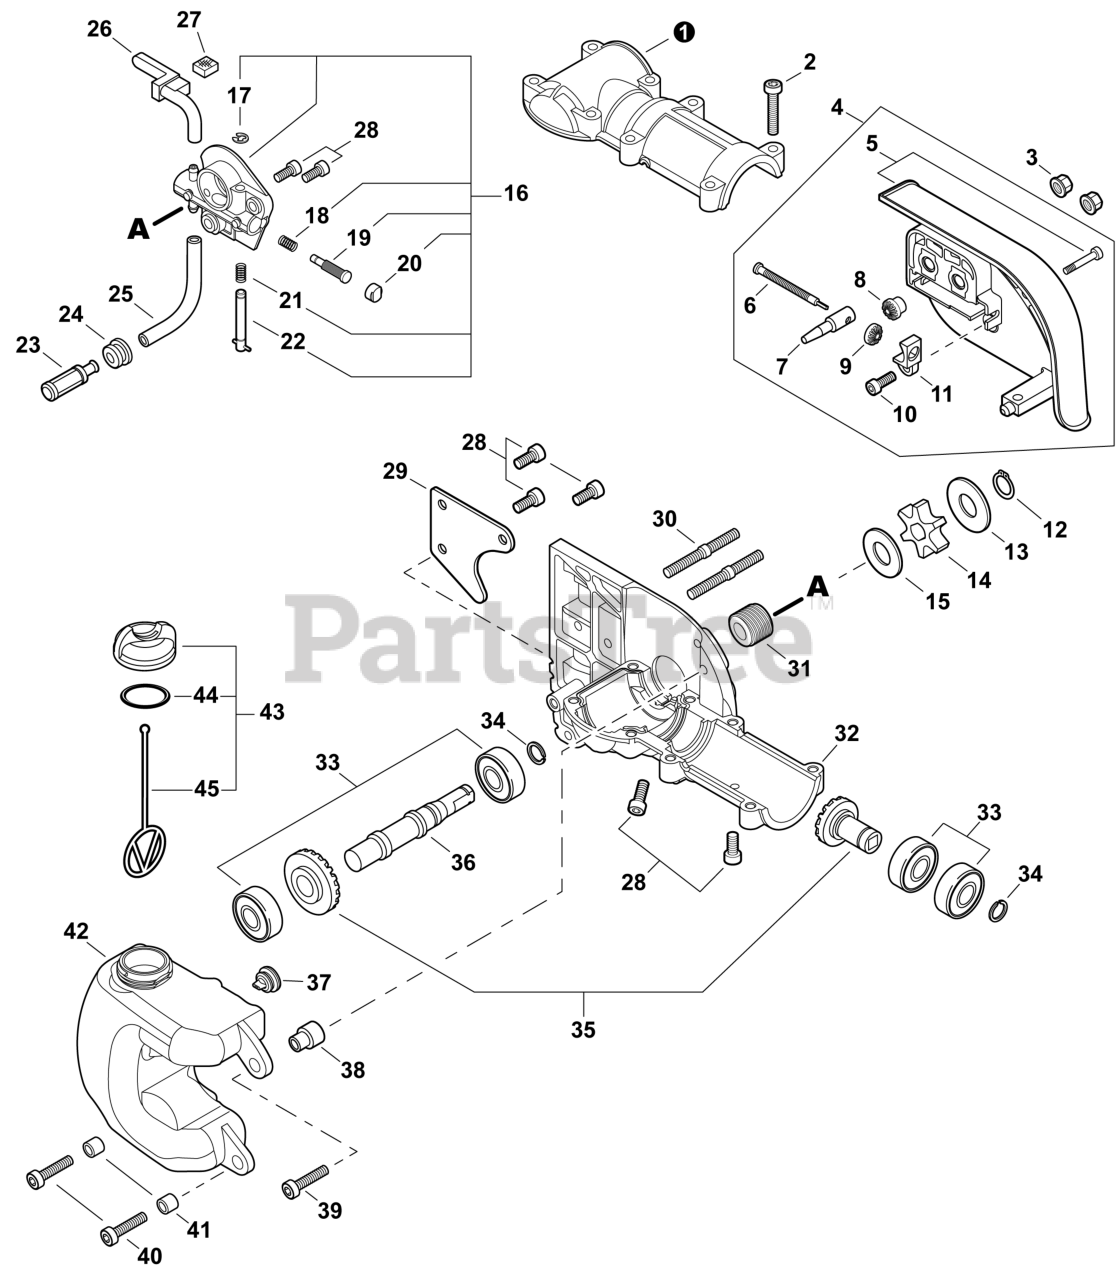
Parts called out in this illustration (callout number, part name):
1	COVER, GEAR CASE
2	BOLT, TORX 5x25
3	NUT, FLANGE M6
4	SPROCKET GUARD ASSY
5	GUARD, SPROCKET
7	TENSIONER, CHAIN
8	GEAR - 14 TOOTH
9	GEAR - 14 TOOTH
10	SCREW 4
11	COLLAR 8
12	RING, SNAP
13	WASHER 10
14	SPROCKET, DRIVE
15	WASHER 10
16	AUTO-OILER ASSY
19	PLUNGER ASSY
20	CAP, PLUNGER
22	ADJUSTER, OILER
23	FILTER, OIL
25	PIPE 3x6x70
26	PIPE, OIL OUTLET
27	PAD, FOAM
28	BOLT, TORX 5x10
30	BOLT, STUD 6
31	GEAR, WORM
32	CASE, GEAR
33	BEARING, BALL
34	RING, SNAP 12
35	GEAR SET
36	SHAFT, GEAR
37	VENT ASSY
38	COLLAR 6
39	BOLT, TORX 5x25
40	BOLT, TORX 5x20
41	SPACER 6.2x7.8x6
42	TANK, OIL
43	CAP ASSY
44	O-RING 18
45	CONNECTOR, CAP L= 60 MM
